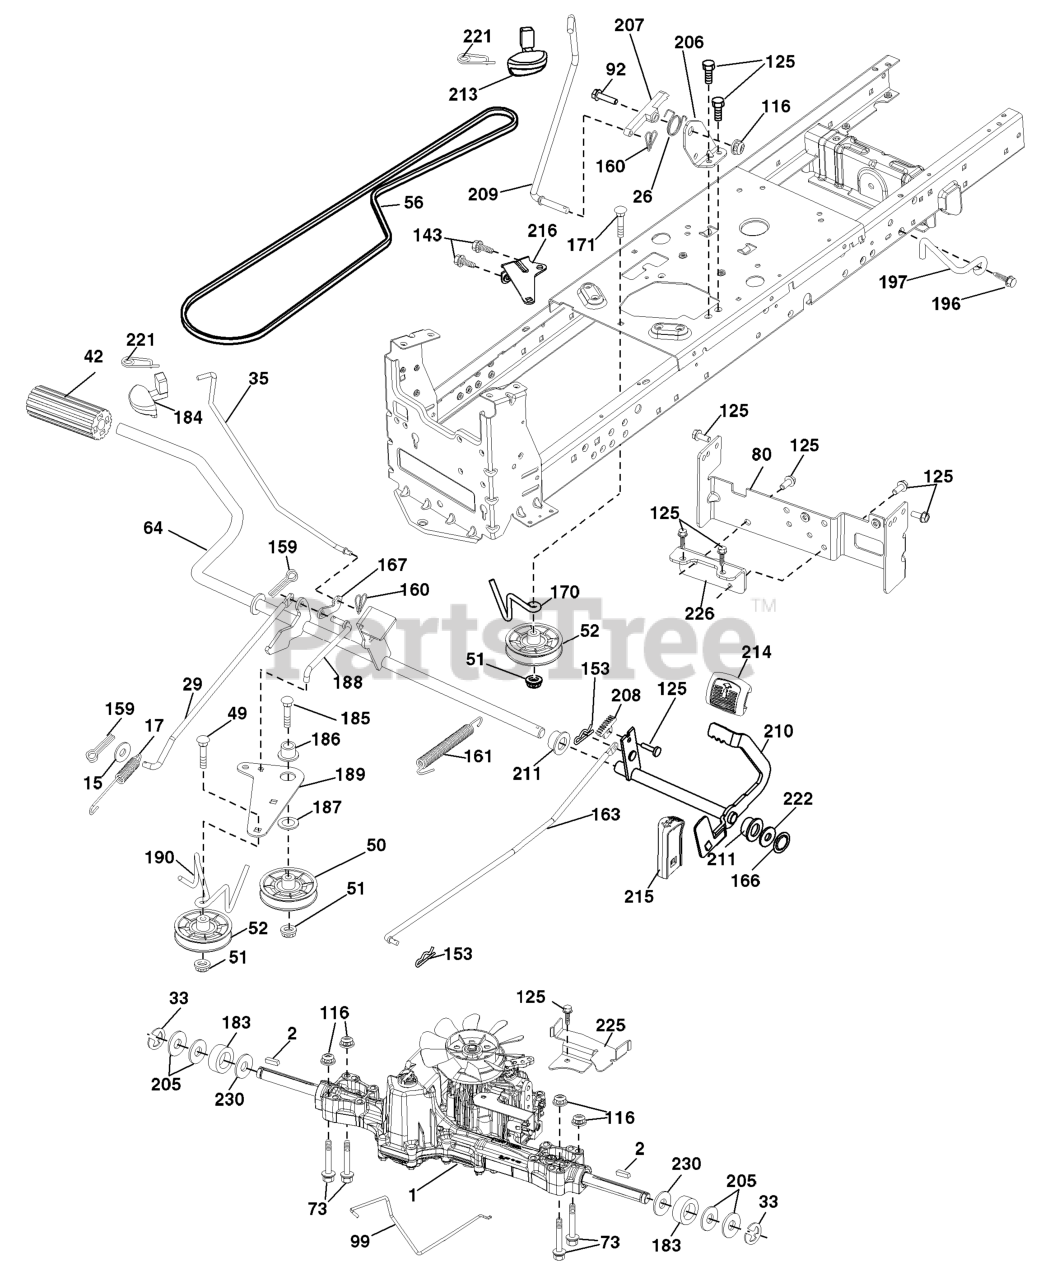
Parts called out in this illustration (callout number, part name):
1	TRANSAXLE, TUFFTORQ K46
2	SQUARE KEY
15	WASHER
17	SPRING.BRAKE.K46.GREEN
26	SPRING.RETURN.CRUISE
29	ROD.BRAKE.K46
35	ROD.BRAKE.PARKING.GT.H
42	PEDAL COVER T
50	IDLER.FLAT.910.OFFSET
51	NUT LOCK FLG 3/8-16 UNC
52	IDLER.V-GROOVE.910.OFFSET
56	V-BELT.MOWER.92.40.42/K46
64	SHAFT.ASM.PEDAL.BRK.CNTR
73	BOLT HEX 5/16-18 GR 5
80	STRAP TORQUE.ASM.K46/18"TEX
92	BOLT
99	ROD.SPRING.BYPASS.K46.LT.Z
116	NUT LOCK HEX FLANGE 5/16-18
125	SCREW
143	Screw 5/16-18 x 1/2
153	RETAINER M
159	COTTER PIN
160	RETAINER CLIP
161	Spring, Return, Clutch
163	ROD.CONTROL.PEDAL.K46
166	NUT.PUSH.625.2006
167	LATCH.BRAKE.SPRING
170	KEEPER.V-IDLER.CENTER.
171	BOLT
183	SPACER AXLE
184	HANDLE.PARKG.BRK.HUSQ X667
185	BOLT
186	SPACER.RETAINER
187	WASHER 12/32X2X10GA
188	RP.LINK.CLUTCH.GROUND.DRIVE
189	BELLCRANK.GROUND.DRIVE.TEX.
190	KEEPER.BELLCRANK.DRIVE
196	SCREW 3/8-16X1
197	LINK.CLUTCH.ANIT-ROTAT
206	BRKT.MOUNT.LATCH.CRUIS
207	LATCH.CONTROL.CRUISE
208	GEAR.SECTOR.CONTROL.CR
209	ROD.CONTROL.CRUISE.GT.
210	ROCKER.ASM.PEDAL.CONTR
211	BEARING.NYLON
213	KNOB.CONTROL.CRUSIE.HU
214	PEDAL.FORWARD.HUSQVARNA.DEALER
215	PEDAL.REVERSE.TEX.GT.4
216	BRACKET.PULLEY.IDLER.W/TEX
221	RETAINER.SPRING.CLIP.H
222	WASHER 21/32 X 1-1/4 X 10 GA.
225	KEEPER.BELT.TRANSAXLE.K46
226	BRACKET.MOUNT.TORQUE.K46.TLT
230	WASHER.HARDENED
